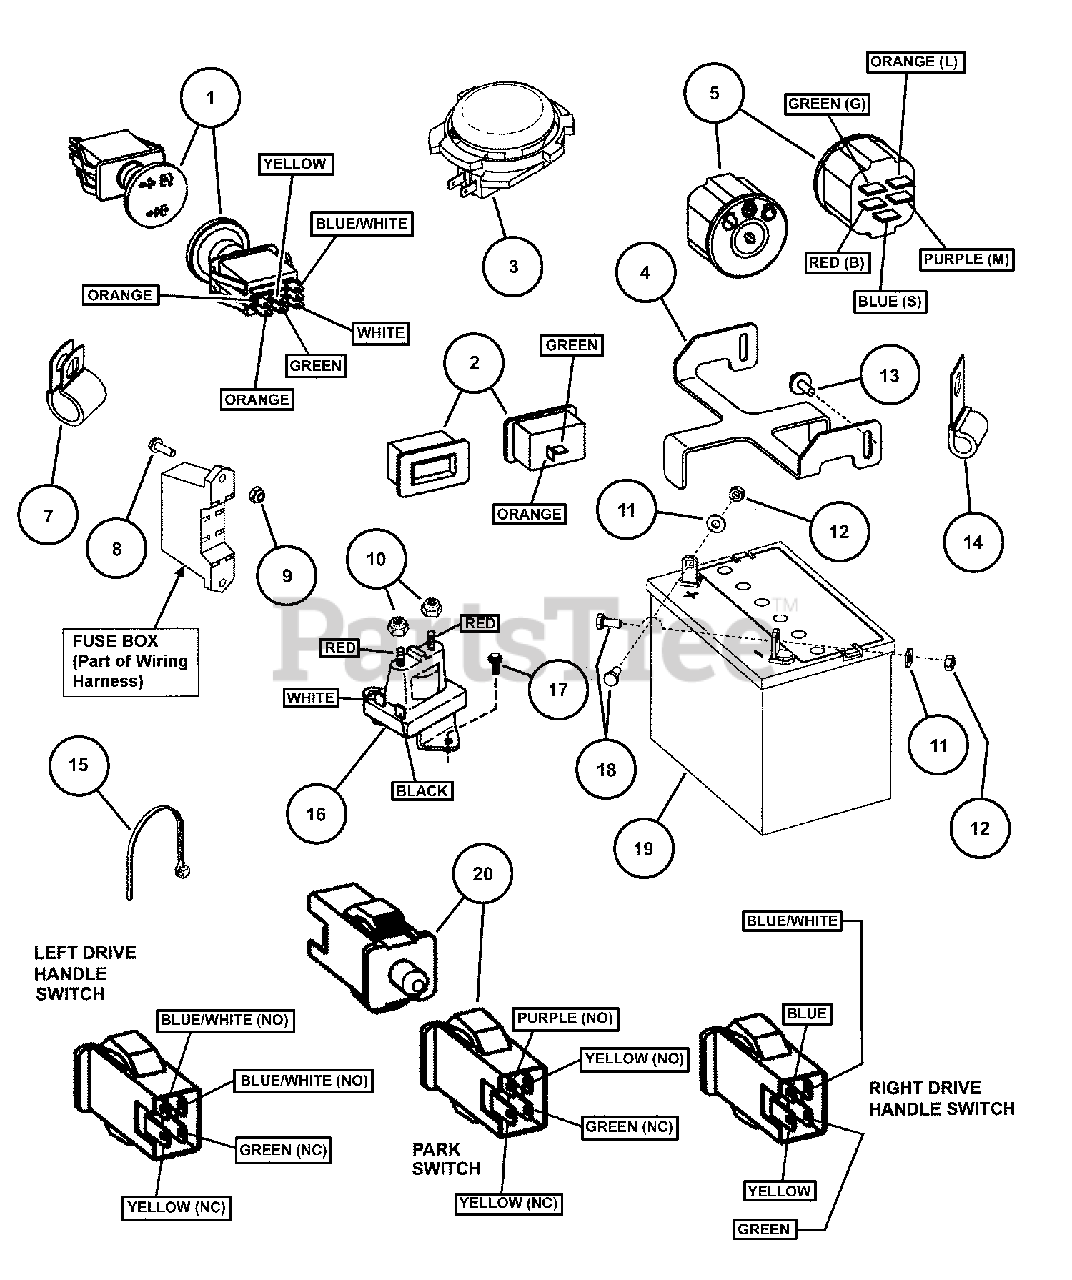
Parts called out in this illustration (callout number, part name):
1	SWITCH, PTO, Yellow
2	HOUR METER w/Flash Alerts
3	SWITCH, Seat, NC
4	BRACKET, Battery Hold-Down
5	SWITCH, Ignition
7	CLIP, Harness
8	SCREW, #10-32 x 5/8" Hex Washer Self-Tap
9	NUT, #10-32 Hex Nyloc
10	NUT, 1/4-20 HEX NYLON LOCK
11	WASHER, 1/4" Flat
12	NUT, 1/4-20 Hex Center Lock
13	SCREW, 1/4-20 x 5/8" Hex Head Self-Tap
14	CLIP, Open 3/8" Cushioned
16	SOLENOID, Super Trombetta
17	SCREW, 1/4-20 x 1/2" Hex Washer Self-Tap
18	SCREW, 1/4-20 x 5/8" Hex Head Cap GR 5
19	BATTERY, 11 Plate 375CCA- Wet
20	SWITCH, DP NO/NC Snap-In
